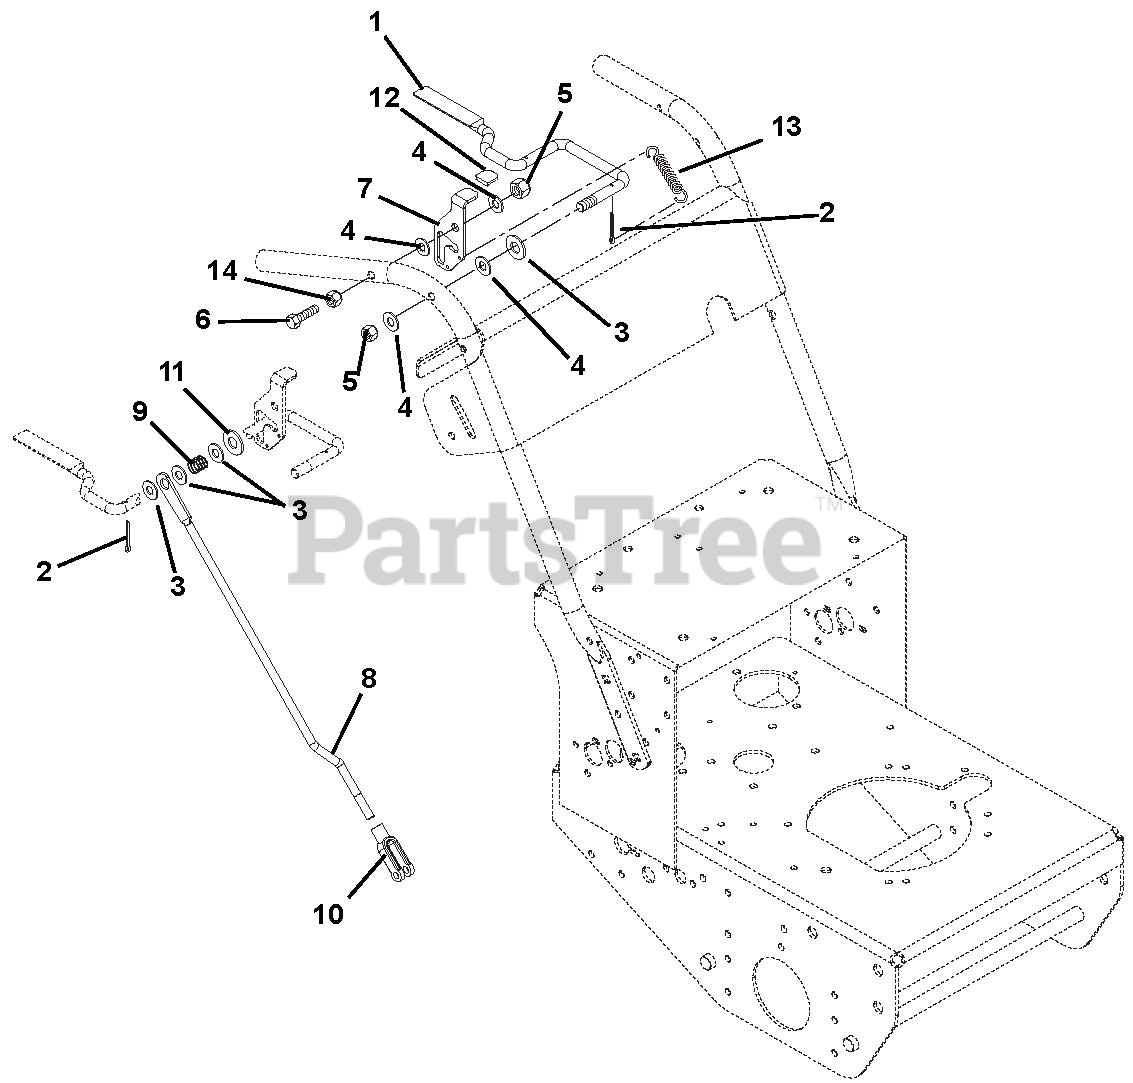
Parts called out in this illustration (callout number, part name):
1	Lever, Hand Control Left Hand
1	Lever, Hand Control Right Hand
2	Pin, Cotter .09 x .75
3	Washer, Flat-Steel .406 x .812 x .065
4	Washer, Flat-Nylon .375 x .75 x .060
5	Nut, Locking-Center .38-16
6	Bolt, Hex .38-16 x 2.50 Grade 2
7	Latch, Right Hand Thumb
7	Latch, Left Hand Thumb
8	Rod, Steering Link
9	Spring-Compression .045 x .60 x .75
10	Clevis, .38-24 Adjustable
11	Washer, Flat-Steel .50 x 1.25 x .083
12	Grip, Thumb Latch
13	Spring, Tension .041 x .50 x 1.75
14	Nut, Locking-Jam-Center .375-16
